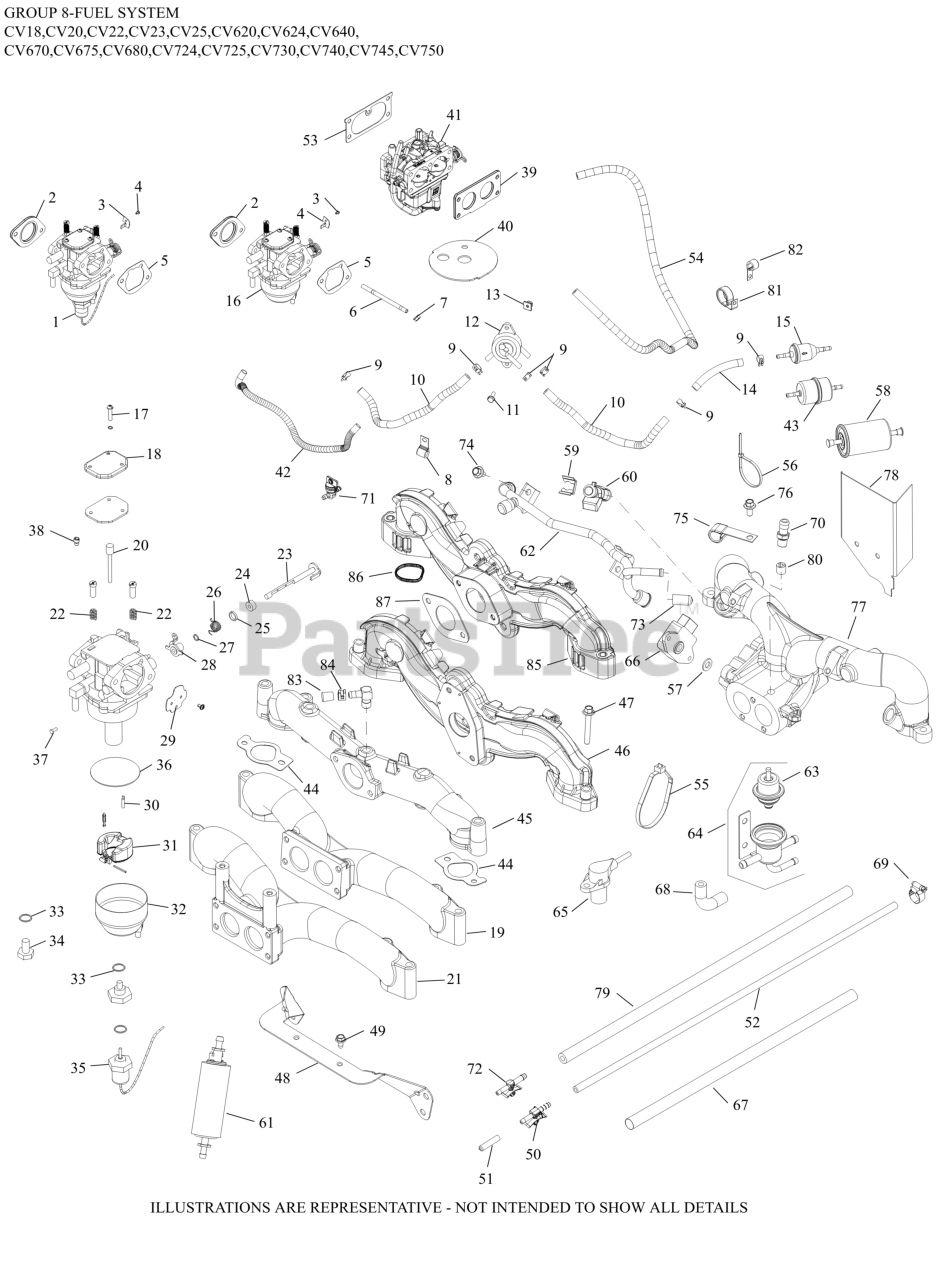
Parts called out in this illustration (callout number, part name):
1	KIT, CARBURETOR W/GASKET
6	STUD,M6X1.0X96
7	NUT, FLG M6X1.0
9	CLAMP, HOSE (KM)-USE 25 237 31-S
9	HOSE CLAMP USE 25 237 14-S
10	HOSE,LW PERM.FUEL 24.00"-USE 25 111 81-S
11	SCREW, TAP M6X1.7X18
12	PUMP, FUEL
13	NUT, PLASTIC - BLACK
23	KIT, REPAIR SERVICE CHOKE
31	KIT, REPAIR OVERHAUL
32	CHAMBER, FLOAT
35	KIT, REPAIR SOLENOID VALVE
36	KIT, REPAIR SERVICE GASKET
43	FILTER, FUEL
80	PLUG, CTSK PIPE 1/8"
NI	KIT, HIGH ALTITUDE NIKKI 4000/8000'
